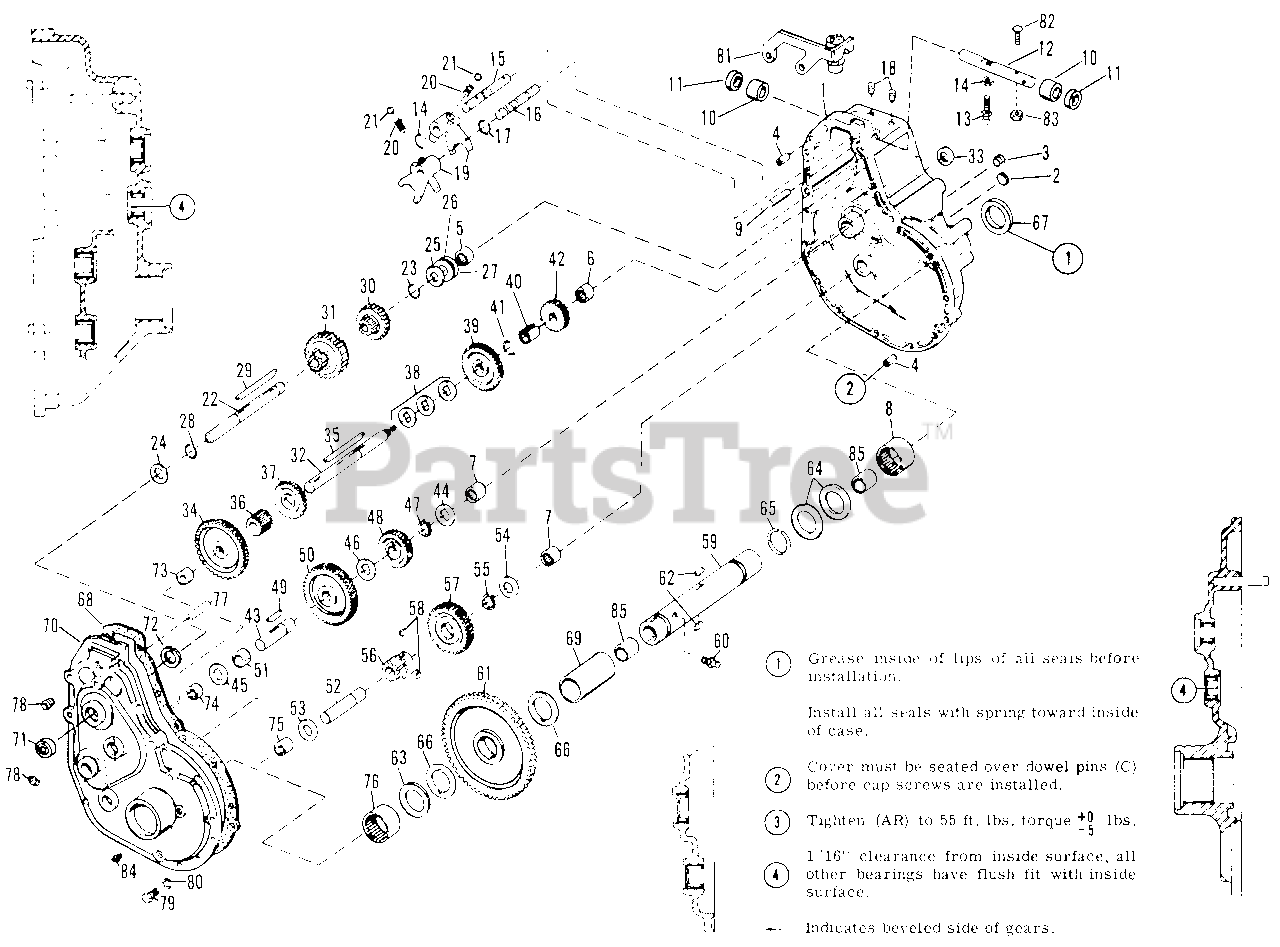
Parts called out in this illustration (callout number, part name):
1	Case, Gear Assy. Complete w/bearings & dowel pins (Includes 2 thru 7)
2	Expansion Plug
3	Set Screw, Cup Pt. Soc. Hd., 3/8"-16 x 3/8"
5	Needle Bearing
6	Needle Bearing
7	Needle Bearing
8	Needle Bearing
12	Shift Rod
13	Shift Stem
14	Full Hex. Nut, 3/8"-24 N.F.
15	Shifter Shaft Rev., Med.
16	Shifter Shaft High, Low
17	Retaining Ring
18	Set Screw, Hollow Head, Cone Pt., 5/16"-18 x 1/2"
21	Shift Lock Ball
22	Pulley Shaft
23	Retaining Ring
28	Retaining Ring
30	Gear Assy., II & IV
31	Pinion Assembly, I & III
32	Shaft, 1st Intm.
34	Driven I, Gear
36	Pinion, 1st Intm.
37	Pinion, Driven, III
38	Trans. Gear Spacer
39	Driven II Gear
41	Retaining Ring
42	Pinion, Reverse, IV
43	Shaft, 2nd Intm.
47	Retaining Ring
48	Pinion, 2nd Intm.
50	Gear, 2nd Intm.
52	Shaft, 3rd Intm.
55	Retaining Ring
56	Pinion, 3rd Intm.
57	Gear, 3rd Intm.
58	Key Woodruff
59	Axle Tube w/bushing
60	Grease Fitting
61	Drive Gear
63	Washer
66	Axle Tube Washer
68	Gear Case Gasket
69	Axle Tube Spacer
70	Gear Case Cover, Complete w/bearings
71	Ball Bearing
72	Retaining Ring
73	Needle Bearing
74	Needle Bearing
75	Needle Bearing
76	Needle Bearing
77	Roll Pin Assembly
78	Pipe Plug, 3/8"
79	Hex Cap Screw, 5/16"-18 x 1"
80	Lock Washer, 5/16"
81	Switch Support
82	Carriage Bolt, 5/16"-18 x 1"
83	Jam Nut, 5/16"-18
84	Pipe Plug, 3/8"
